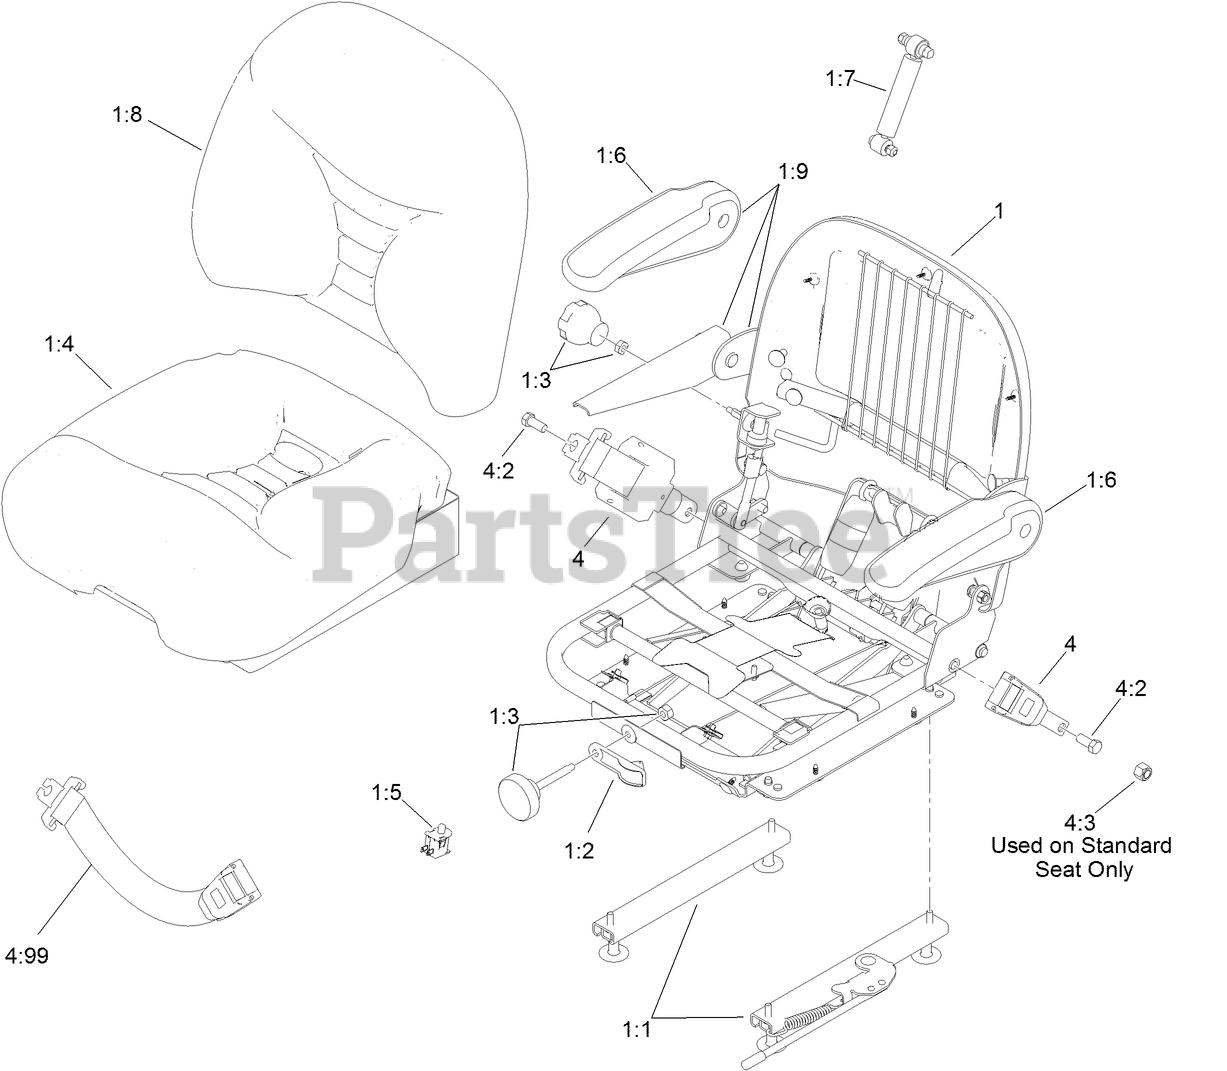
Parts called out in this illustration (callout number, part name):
1	SEAT-SUSPENSION
1:1	Seat Track Kit
1:2	Weight Indicator Kit
1:3	Knob Kit
1:4	Bottom Cushion Kit
1:5	SWITCH-BAIL
1:6	PAD-ARMREST
1:7	Shock Absorber Kit
1:8	CUSHION-BACK
1:9	ARMREST KIT
4	RETRACTABLE SEATBELT KIT
4:2	SCREW-HH
4:3	NUT-LOCK
4:99	SEAT BELT EXTENSION KIT
